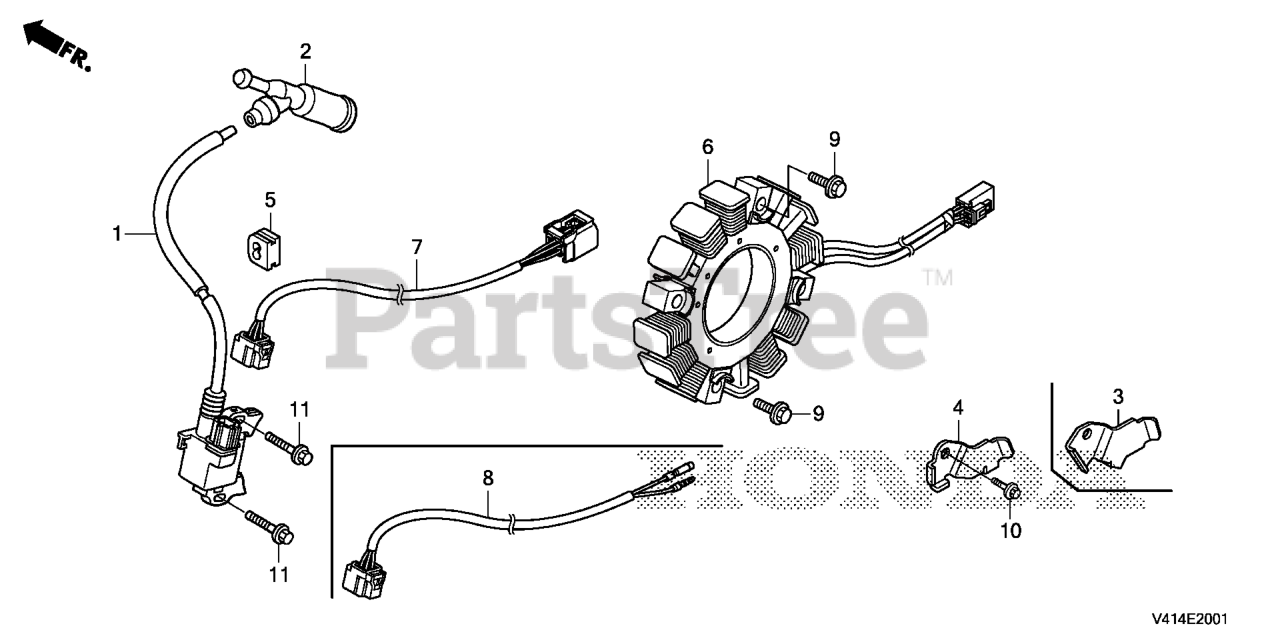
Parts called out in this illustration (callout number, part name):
1	COIL ASSY., IGNITION
2	CAP ASSY., NOISE SUPPRESSOR (NGK Y-EZD)
4	CLAMP, WIRE
5	GROMMET, WIRE
6	COIL ASSY., CHARGE
7	WIRE HARNESS ASSY., ENGINE
9	BOLT, FLANGE (6X32)
10	BOLT, FLANGE (6X12) (CT200)
11	BOLT, FLANGE (6X28) (CT200) Use up to Engine SN 1530314.
